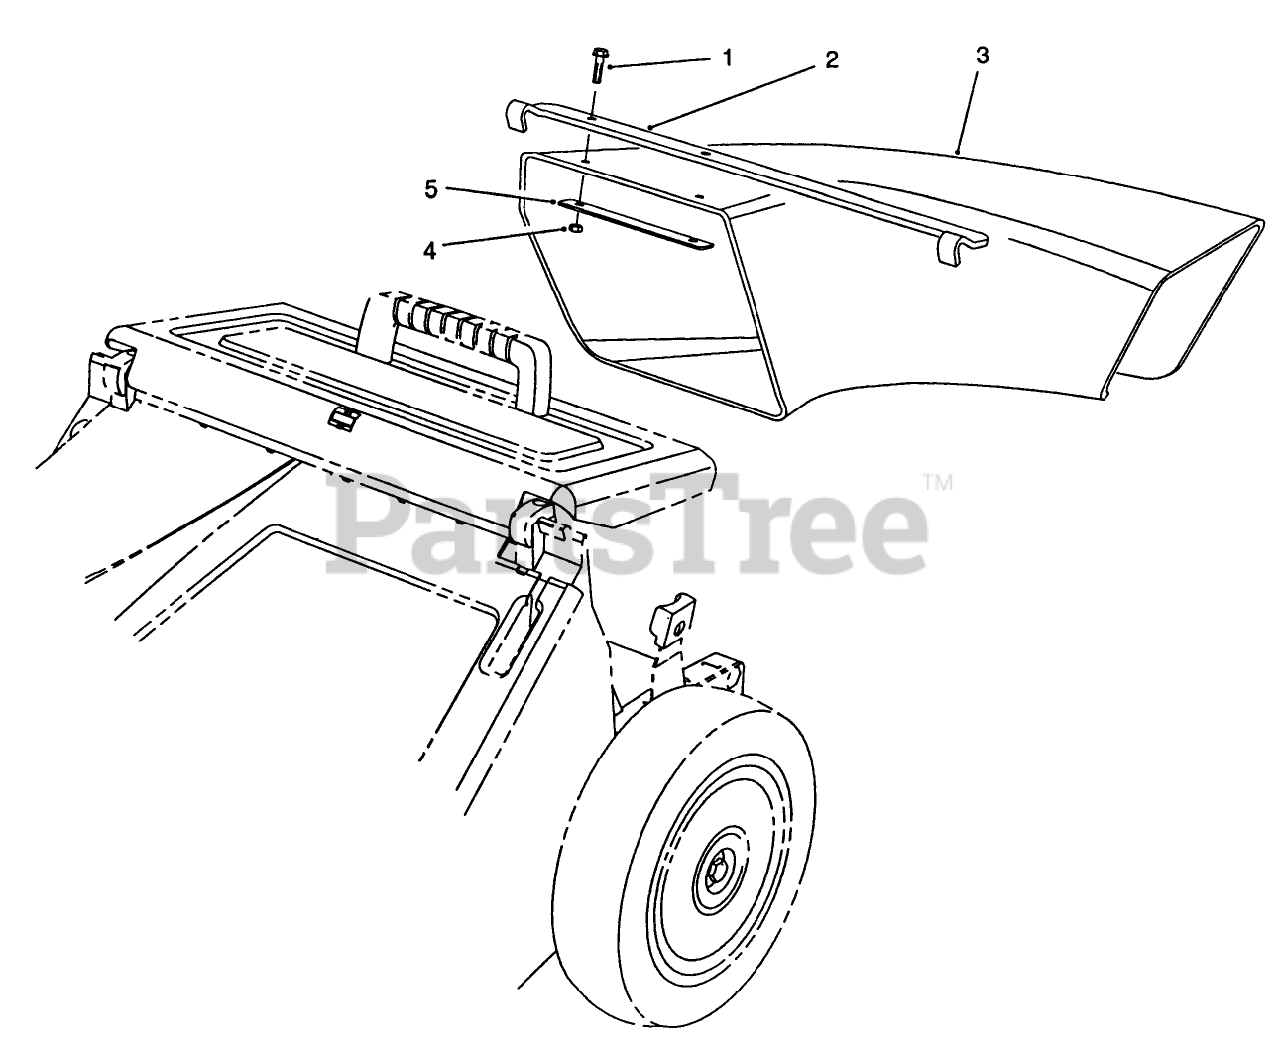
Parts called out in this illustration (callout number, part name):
1	SCREW-HWH
2	CHUTE HANGER BRACKET*
4	NUT-LOCK, NI
